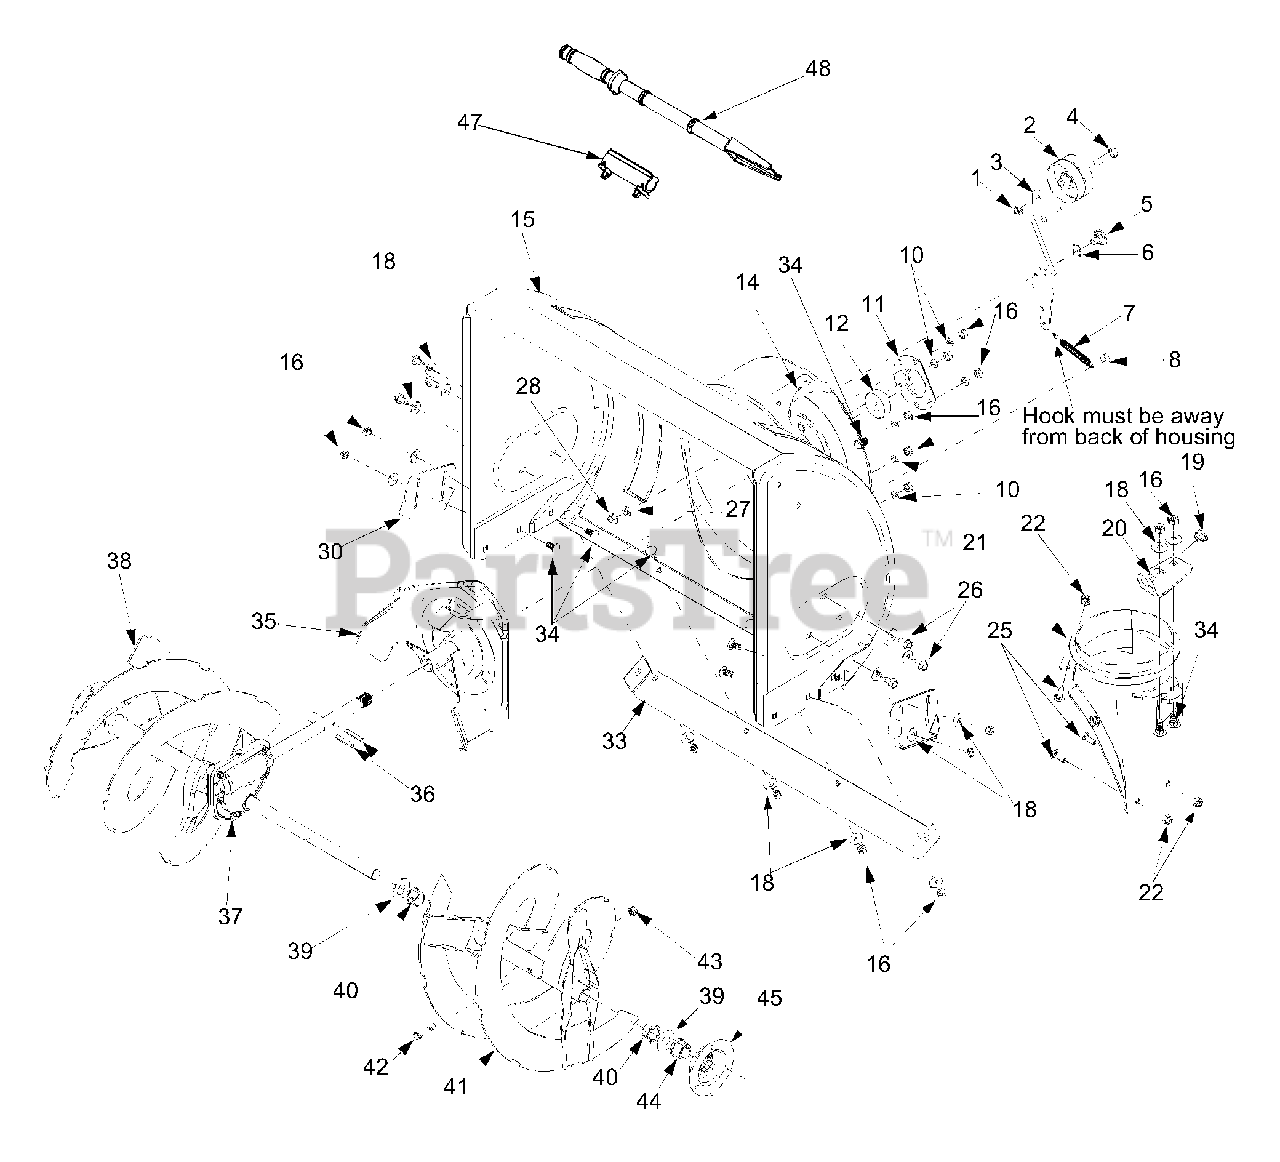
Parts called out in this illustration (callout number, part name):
1	Lock Jam Nut 3/8-24
2	Flat Idler
4	Hex Cap Screw 3/8-24 x 1.50
5	Shoulder Screw
6	Wave Washer
7	Extension Spring
8	Hex Nut 5/16-18
10	Lock Washer 5/16
11	Housing
12	Ball Bearing
18	Bell Washer
19	Bushing
21	Chute Adapter
22	Hex Flange Lock Nut 1/4-20
25	Carriage Screw 1/4-20 x.75
26	Screw 5/16-12
27	Lock Washer 3/8
28	Hex Nut 3/8-16
34	Carriage Bolt 5/16-18 x.62
37	22" Gear Assembly
40	Flange Bushing
42	Shear Bolt 5/16-18 x 1.5
43	Lock Nut 5/16-18
44	Hex Flange Bearing
47	Clean-Out Tool Mount
48	Clean-Out Tool
